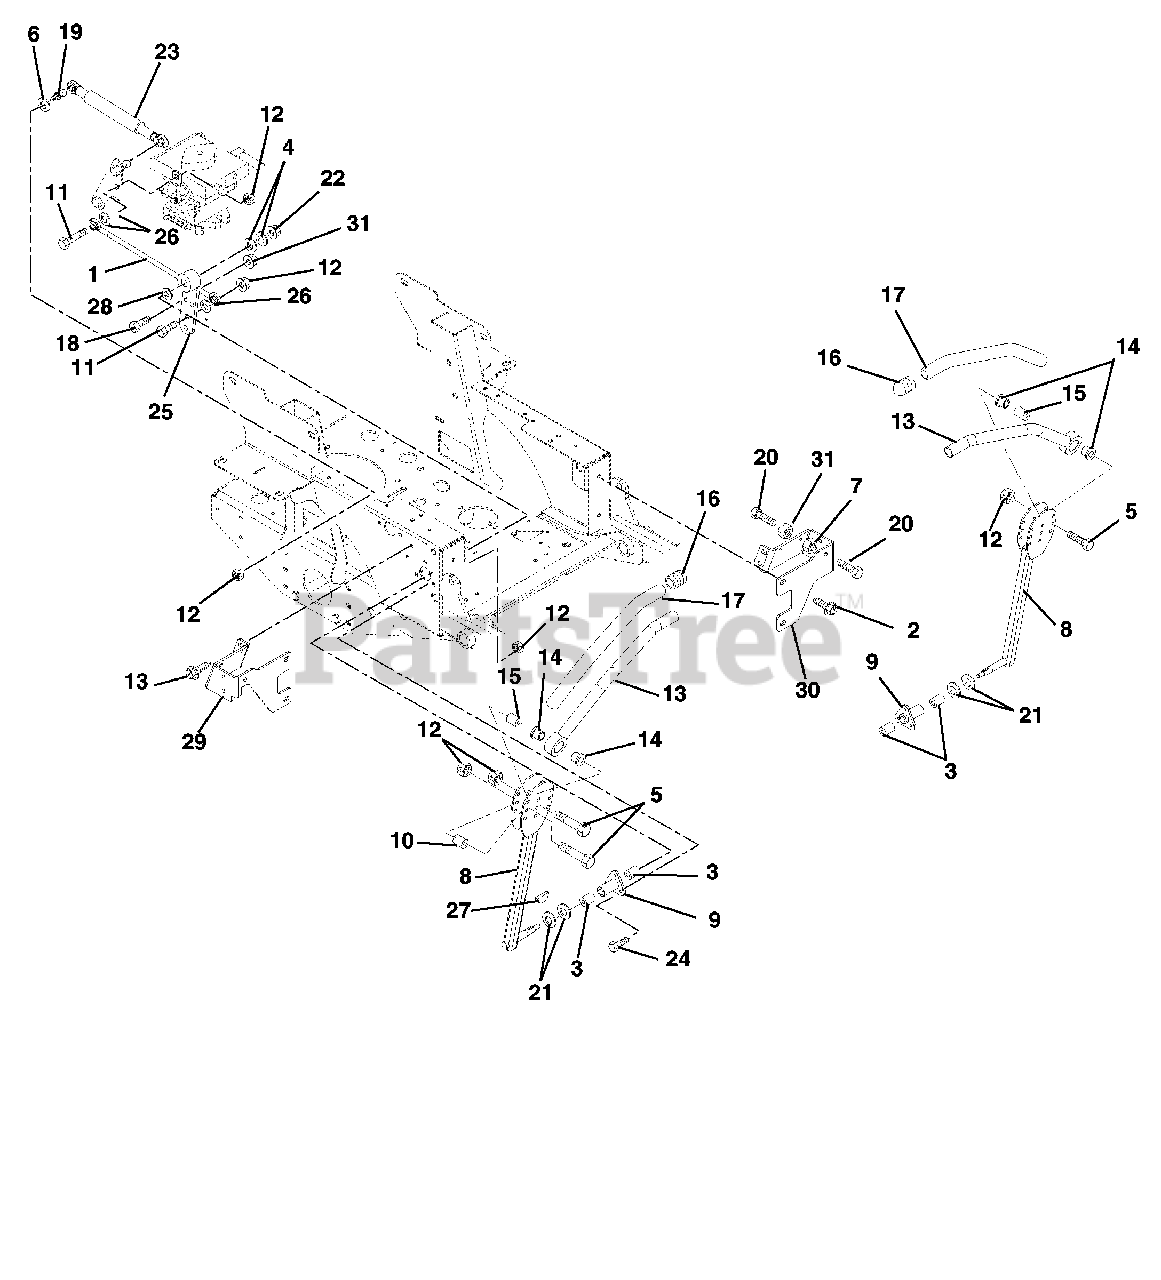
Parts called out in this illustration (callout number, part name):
1	Assembly, Steering Rod
2	Screw, Tapping .38-16 x .75 Hex Washer Head
3	Bushing .625 x .75 x .50
4	Washer, Flat Steel .406 x .812 x .065
5	Bolt, Hex .31-18 x 1.75 Grade 5
6	Washer, Flat Steel .344 x .688 x .065
7	Nut, Hex Jam .375-16
8	Control Arm
9	Housing, Bushing
10	Eccentric
11	Bolt, Hex .31-18 x 1.25 Grade 5
12	Nut, Locking Top Flange .31-18
13	Handle Weldment Left-Hand
13	Handle Weldment Right-Hand
14	Bushing, Flange Nylon .762 x 1.48 x .44
16	Caplug, Handlebar
17	Grip, Handlebar
18	Bolt, Hex .375-16 x 1.75
19	Stud, Ball
20	Bolt, Hex .38-16 x 1.25 Grade 5
21	Washer, Flat Steel .63 x 1.005 x .062
22	Nut, Locking Top Flange .38-16
23	Dampener, Control
24	Bolt, Hex .31-18 x .75 Grade 5
25	Weldment, Pivot Arm
26	Washer, Locking .31 x .078 Regular
27	Key, Woodruff .13 x .63
28	Wave Washer
29	Stop, Steering-Right Hand
30	Stop, Steering-Left Hand
31	Nut, Locking Jam Center .375-16
